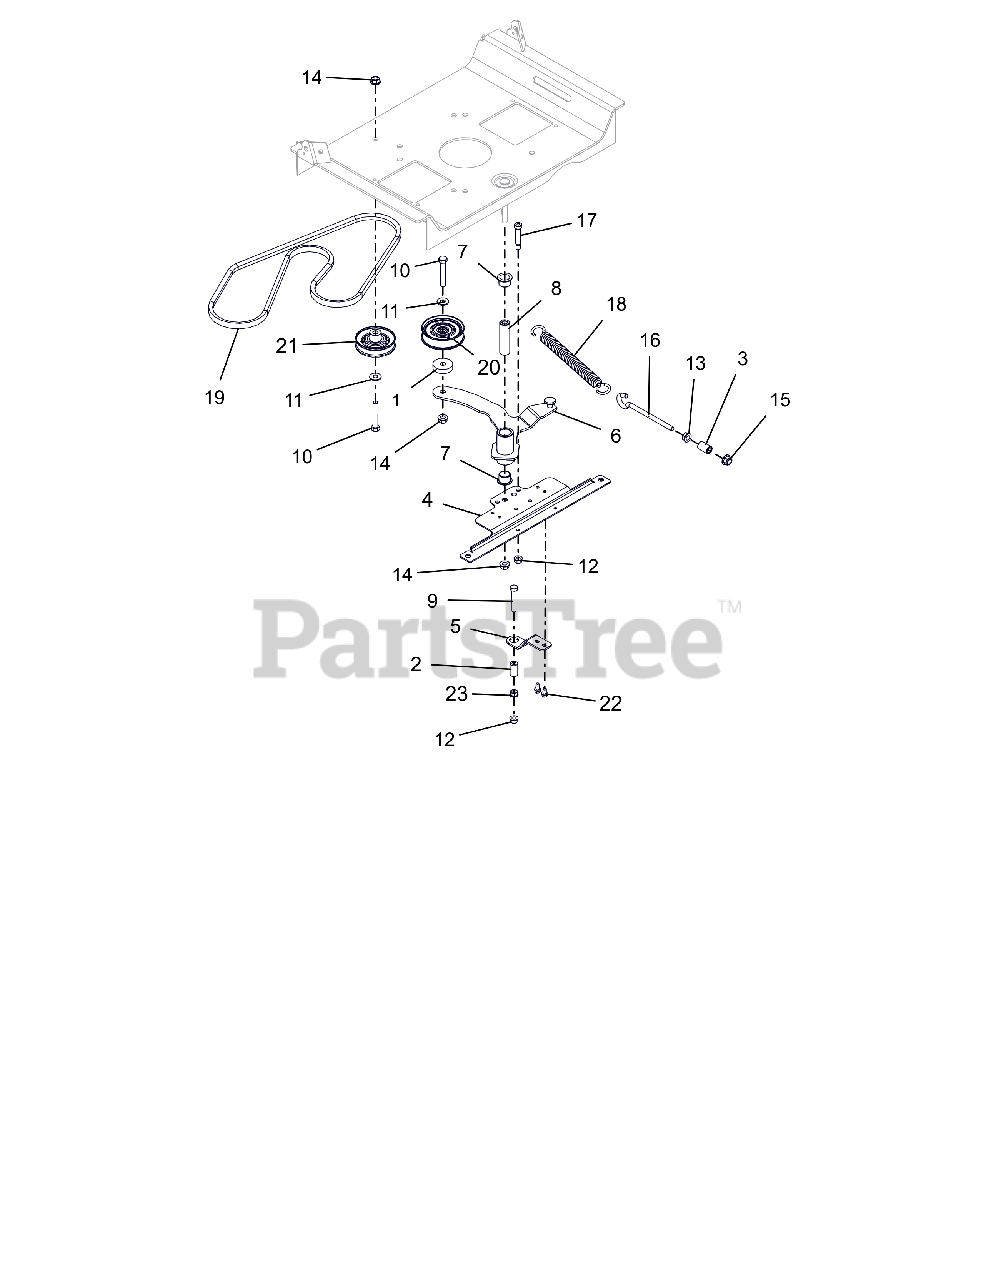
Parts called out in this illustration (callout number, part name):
1	SPACER, .39 X 1.50 X .380
2	SPACER, RUBBER 5/16 IDX1.0 LG
3	SPACER, .375X.625X.970 (PM)
4	BRKT, DRIVE IDLER MOUNTING
5	BRKT, CLUTCH STOP (XL)
6	WLDMT,GRD DRIVE IDLER ARM-LGR
7	BSHG-FLG 0.75X0.875X.625X1.125
8	BUSHING, SLEEVE .38X.750X2.78
9	BLT, HEX .31-18X2.00 G5 ZCC
10	BLT,HEX .38-16X2.25 G5 ZCC
11	WSHR,FLT .375X.875X.083 ZCC
12	NUT-LK-TOP-FLG .312-18 GF ZCC
13	NUT, SPNLK-FLG .38-16 G5 ZCC
14	NUT-LK-TOP-FLG .38-16 ZC120
15	NUT,NYL-FLG .38-16 GF ZCC
16	BOLT,.38-16 X 4.25-.62 DIA EYE
17	BLT-SHLDR .38X1.5X.31-18 SLT Y
18	SPRING, EXTENSION
19	V-BELT, A-RAW EDGE
20	IDLER, FLAT - 3.05" X .75"
21	IDLER, V-3.000 OD
22	SCR-TAP .25-20X.50 HWH ZCC
23	NUT,SPNLK-FLG .31-18 G5 ZCC
